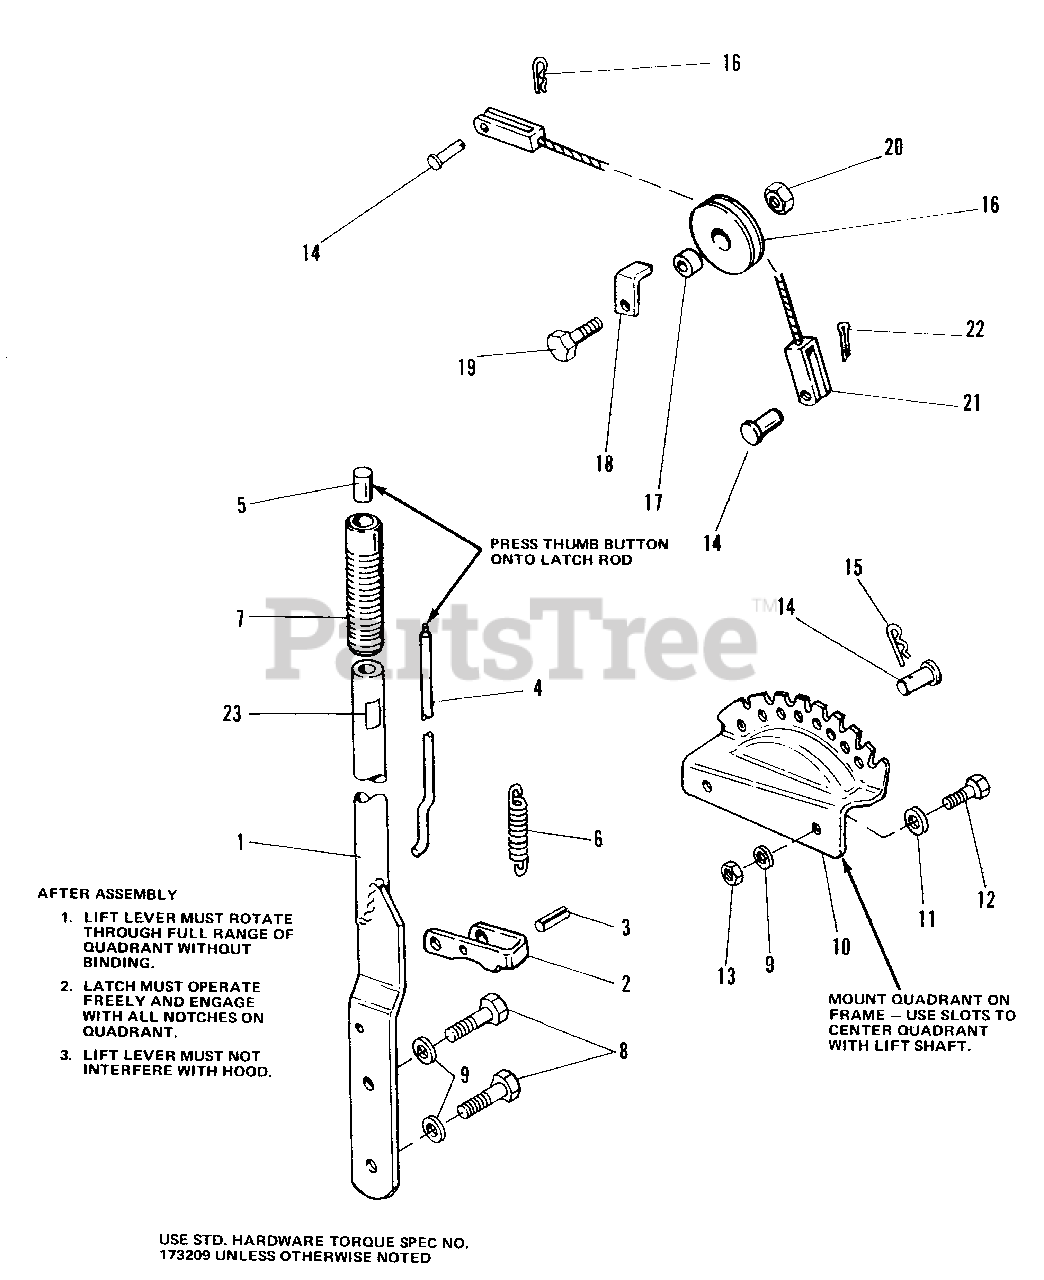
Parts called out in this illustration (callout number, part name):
1	LIFT LEVER ASSEMBLY
2	LATCH, Lift Lever
3	PIN, Spring, 3/8 x 1-1/4
4	ROD, Latch
7	GRIP
8	CAPSCREW, Hex Hd., 3/8-16 x 1
9	LOCKWASHER, 3/8
11	WASHER, 5/16
12	CAPSCREW, Hex Hd., 3/8-16 x 1
13	NUT, Hex, Full, 3/8-16
15	CLIP, Spring
18	**GUARD, Cable
20	LOCKNUT, Hex, Jam, 3/8-16
21	LIFT CABLE ASSY
22	PIN, Cotter, 3/32 x 7/8
23	DECAL, Lift Lever
